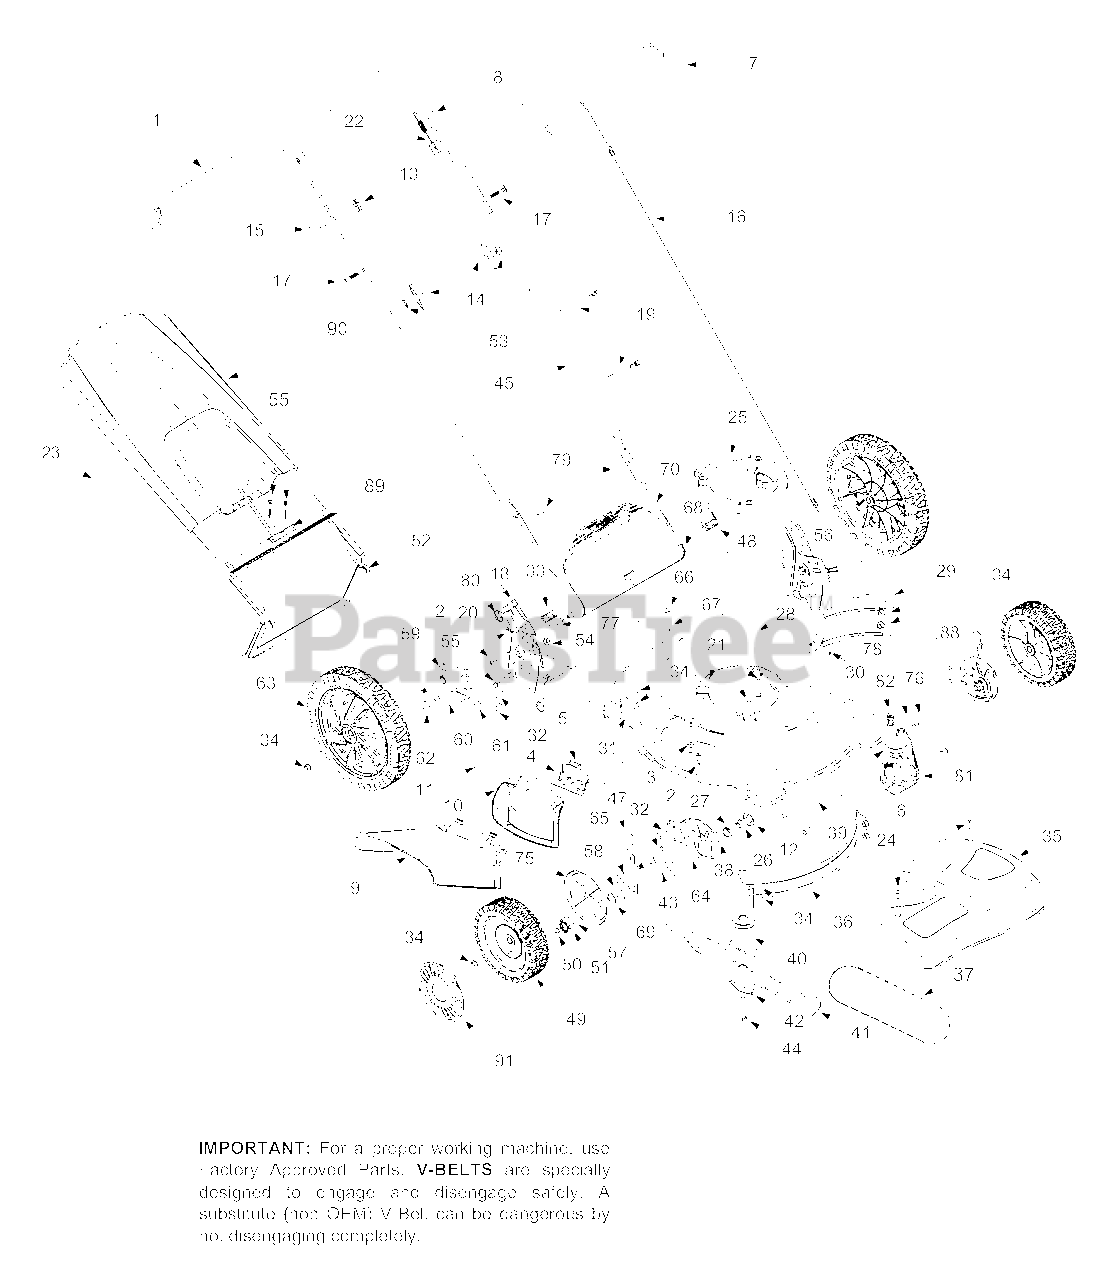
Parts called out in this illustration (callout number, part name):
1	Lower Bail Handle
2	TT Screw 1/4-20 x 0.5
3	Bell Washer.265 x 0.75
4	Deflector Chute Adapter
5	Torsion Spring
6	Input Pulley
7	Blade Control Handle
8	Upper Handle
9	Chute Deflector
10	Mulch Plug Complete
11	Hinge Pin
12	Bearing Retainer
13	Handle Knob
14	Handle Knob
15	Eye Bolt
16	Control Cable - 50.56"
17	Carriage Bolt 5/16-18 x 2.0
18	RH Handle Bracket
18	LH Handle Bracket
19	Cable Tie
20	Cotter Pin
21	Self-Tapping Sems Screw
22	Drive Cable - 50.50"
23	Grassbag Assembly
24	Shoulder Screw # 12 -24
25	Engine Spacer
26	Bearing Sleeve
27	Bearing Support
29	LH Rear Baffle
30	Screw AB: 1/4-14:.625
31	RH Rear Baffle
32	Hex Screw 3/8-16 x.75
33	Torsion Spring RH
34	Flange Lock Nut 3/8-16
35	Transmission Cover (Yellow)
36	Front Baffle
37	V-Belt
38	Wave Washer
39	Sleeve Spacer 9.04" Lg.
40	Blade Adapter w/ Pulley
41	21" Mulching Blade
42	Blade Bell Support
43	Pivot Plate Assembly
44	Hex Screw 3/8-24 x 2.50
45	Lower Handle
47	Adjustment Knob
48	Torsion Spring LH
49	Wheel 8 x 2.125
50	Snap Ring
51	Gear 14T RH FWD
52	Grass Bag Frame
53	Saddle Washer
54	Hex Flange Lock Nut 3/8-16
55	TT Scr. w/Washer 1/4-20 x.625
56	RH Handle Bracket Assembly
56	LH Handle Bracket Assembly
57	Dowel Pin
58	Washer
59	Pivot Arm Assembly - RH
59	Pivot Arm Assembly - LH
60	Rear Spring Lever
61	Foam Grip
62	Shoulder Scr.500 Dia. x.434
63	Wheel, 12 x 2.125
64	Height Adjuster Plate - RH
64	Height Adjuster Plate - LH
65	Front Lever - RH
66	Wire
67	Rear Trailing Shield
68	Pivot Rod
69	Snap Ring
70	Rear Discharge Door
75	Wheel Dust Cap
76	Slev. Spacer 2.1" Lg.
77	Spacer .375 x.50 x 1.02" Lg.
78	Roll Pin
79	Carriage Bolt 1/4-20
80	Wing Nut
81	Transmission Assembly
82	Belt Tension Spring
88	Height Adjustment Assembly RH
